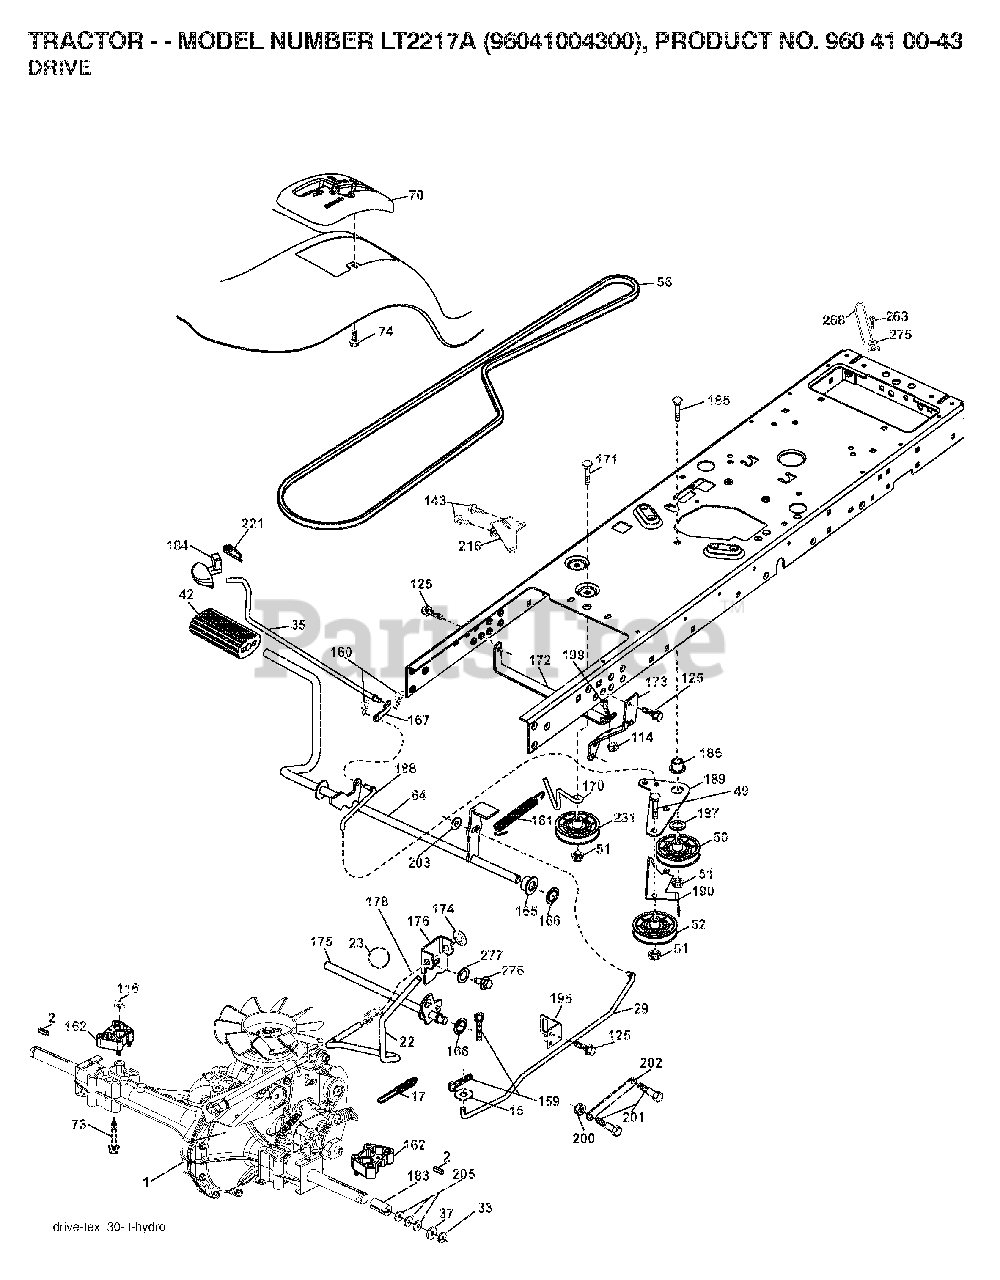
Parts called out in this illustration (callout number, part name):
2	SQUARE KEY
17	SPRING.BRAKE.HG3000/3500
22	ROD.SHIFT.FENDER.TLT.2006
23	KNOB.DUCKHEAD.1/2
29	ROD.BRAKE.HG-0510
33	E-RING LT
35	ROD.BRAKE.PARKING.LT.T
42	PEDAL COVER T
49	BOLT
50	IDLER.FLAT.910.OFFSET
51	NUT LOCK FLG 3/8-16 UNC
52	IDLER.V-GROOVE.910.OFFSET
64	SHAFT.ASM.PEDAL.BRAKE.
70	CONSOLE.SHIFT.STL.HYD.BLACK
73	BOLT.HEX.FLNG.5/16-18X3.75
74	SCREW.HI-LO.CONSOLE
114	NUT.71038.31-18.HEX.NYLOCK
116	NUT LOCK HEX FLANGE 5/16-18
125	SCREW
159	COTTER PIN
160	RETAINER CLIP
161	SPRING.RETURN.CLUTCH.2006
162	SPACER.TRANSAXLE.18&22
165	BUSHING.SHAFT.BRAKE.HAND
166	NUT.PUSH.625.2006
167	LATCH.BRAKE.SPRING
170	KEEPER.V-IDLER.CENTER.
172	STRAP.TRQ.LH.FS.HG0510
173	STRAP TORQUE RH
174	NUT.PUSH.500.2006
175	SHAFT.ASM.SHFT.HG0510/
176	ARM.CLEVIS.ROD.SHIFT
178	SPRING.SHIFT.GT2006
183	SPACER AXLE
184	HANDLE.PAKRING.BRAKE.
186	SPACER.RETAINER
187	WASHER 12/32X2X10GA
188	LINK.CLUTCH.GROUND.DRIVE
189	BELLCRANK.GROUND.DRIVE.TEX.
190	KEEPER.BELLCRANK.DRIVE
195	BRKT.ROD.BRAKE.18/20/2
199	BOLT
200	NUT.CENTERLOCK.5/16-
201	BOLT SHOULDER 5/16-18 UNC
202	LINK TRANS
203	WASHER
216	BRACKET.PULLEY.IDLER.W/TEX
221	RETAINER.SPRING.CLIP.H
231	IDLER.V-GROOVE.1.688.OFFSET
263	SCREW, 3/8-16X3/4
275	WASHER
276	BOLT FIN HEX 7/16-14 X 1
277	WASHER SERRATED
